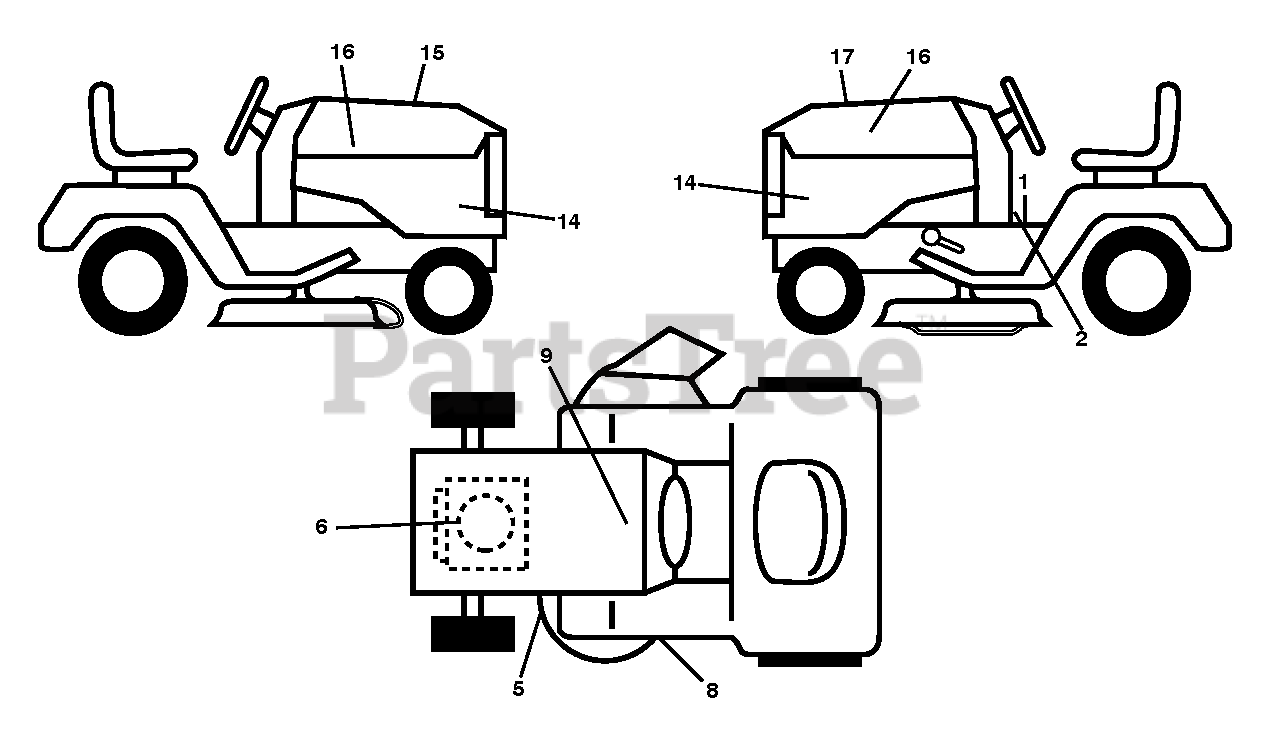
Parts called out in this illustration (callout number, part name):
1	DECAL.FENDER.WARNING
2	DECAL, WARNING SPARK ARRESTOR
5	DECAL.MOWER
6	DECAL.ENG.BS.23HP.XRD
8	DECAL.MOWER.SCH.48/54
9	DECAL BTRY SYMBOLS
14	DECAL.SDPNL.YTH2348.BS.SET.HUS
15	DECAL.WARNING.CUST.RESP.E85.
16	RP.DECAL.BADGE.170MM.TEXTLOGO
17	Decal, Replacement BSM44 INK TLW 48 K46
